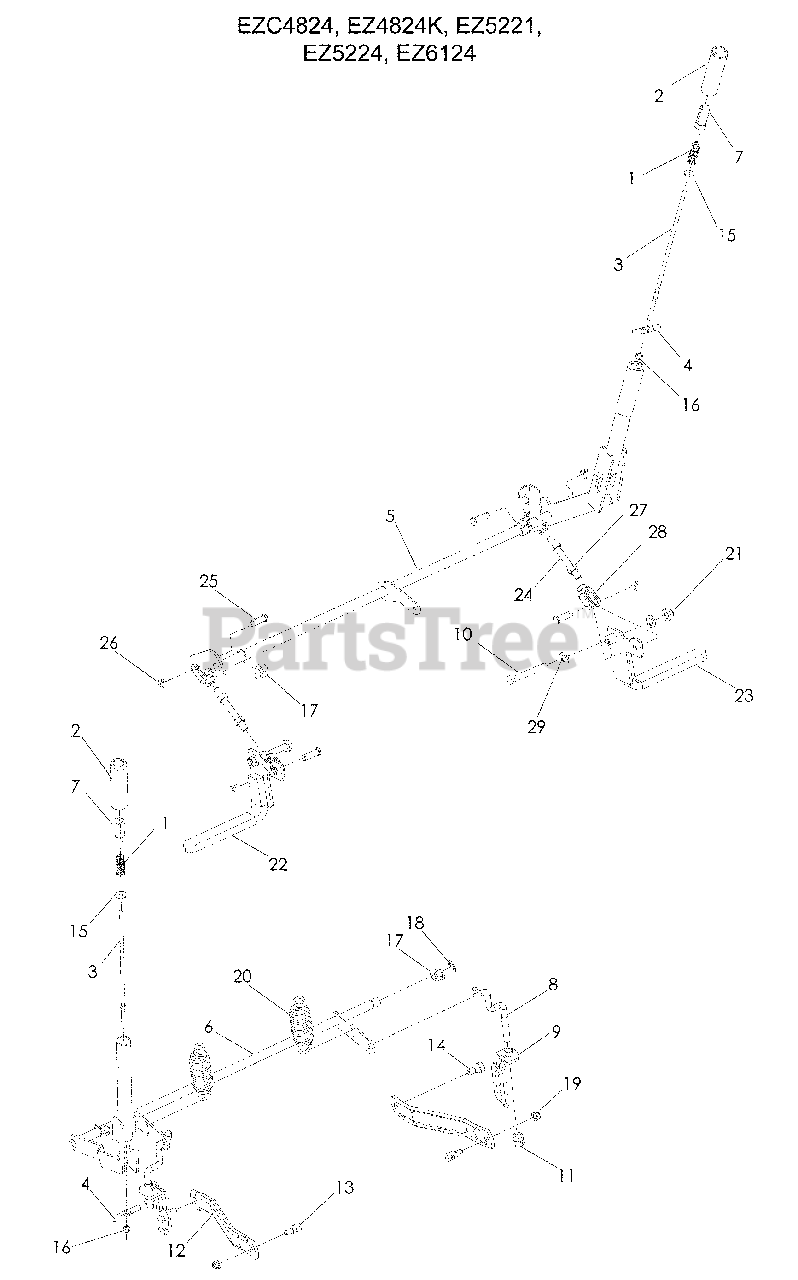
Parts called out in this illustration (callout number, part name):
1	SPRING, COMPRESSION
2	GRIP, HANDLE
3	ROD, HANDLE RELEASE
4	ROD, LATCH RELEASE
5	SHAFT, BRAKE
6	SHAFT, LIFT
7	BUTTON, PUSH
8	LINK, REAR SUSPENSION
9	BRACKET, CENTERING LNK
10	HCS 3/8-16 x 3
11	NUT, LIFT LINK
12	ARM, SUSPENSION RR
13	STUD, w/ANTI- ROTATE
14	BOLT 3/8-16 x 3/8 SKT HD
15	WASHER ¼ FLAT
16	NUT ¼-20 HEX NYLOC
17	PLASTIC NUT
19	NUT 5/16-18 FLANGE NYLOC
21	NUT 3/8-16 HEX JAM NYLOC
24	ROD, THRD 3/8-24
25	CLEVIS PIN
26	PIN, COTTER 1/8 x ¾
27	NUT 3/8-24 HEX GR2
28	YOKE 3/8 SHORT
29	WASHER 3/8 SAE FLAT
